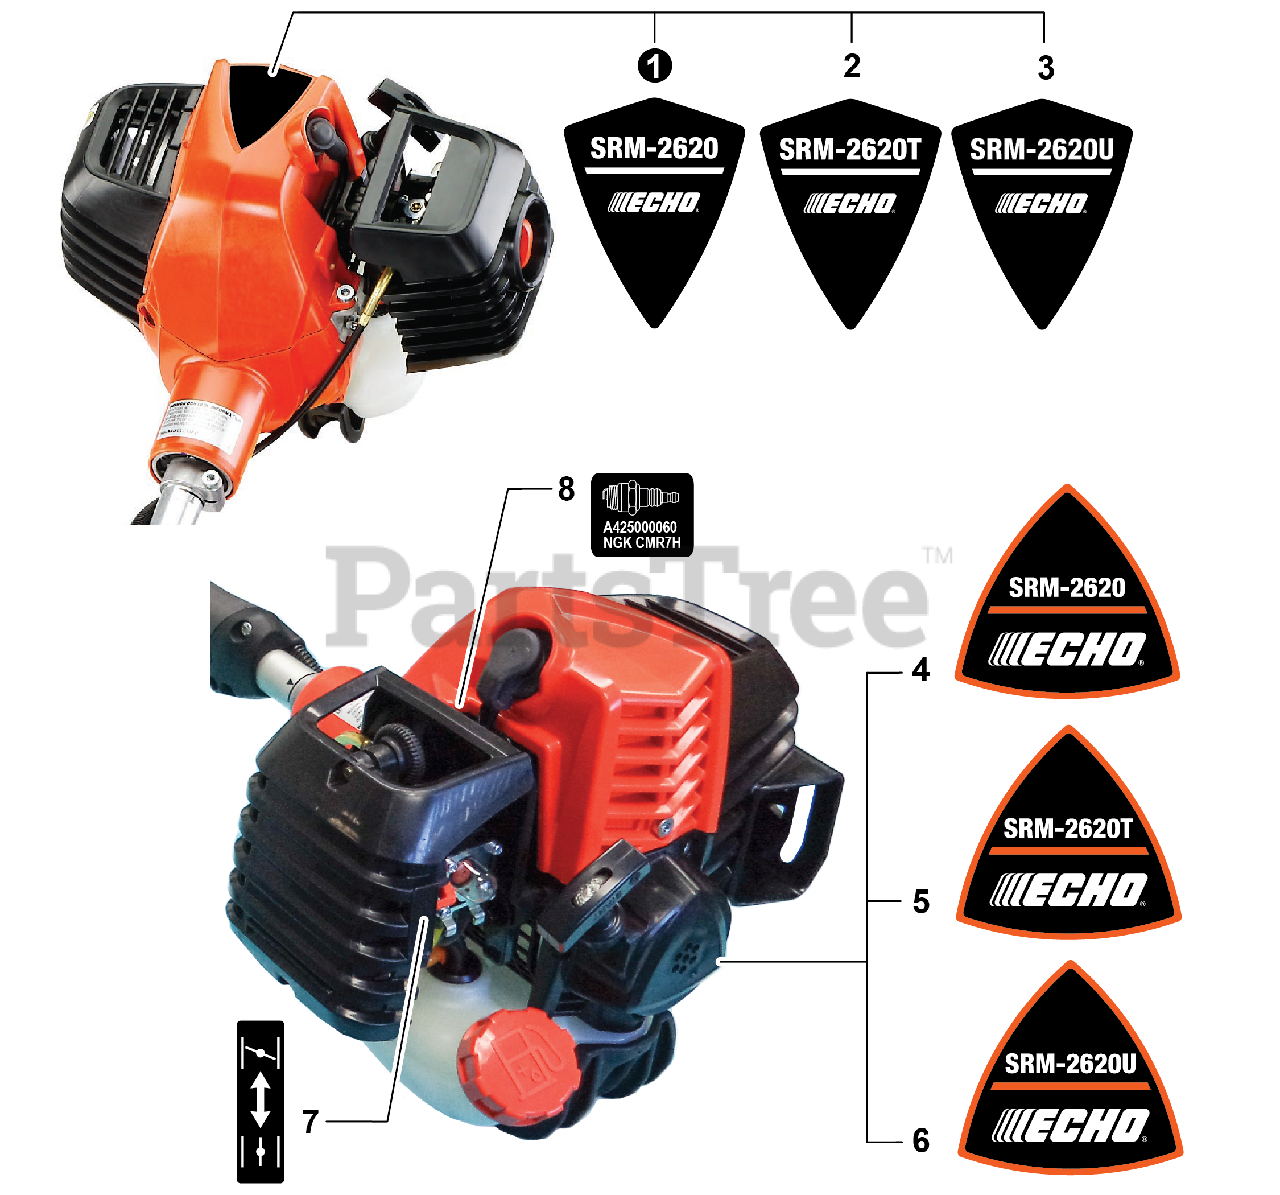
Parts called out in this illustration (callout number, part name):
1	LABEL - MODEL SRM-2620
2	LABEL - MODEL SRM-2620T
3	LABEL - MODEL SRM-2620U
4	LABEL, STARTER - SRM-2620
5	LABEL, STARTER - SRM-2620T
6	LABEL, STARTER - SRM-2620U
7	LABEL, CHOKE
8	LABEL, SPARK PLUG - CMR7H
